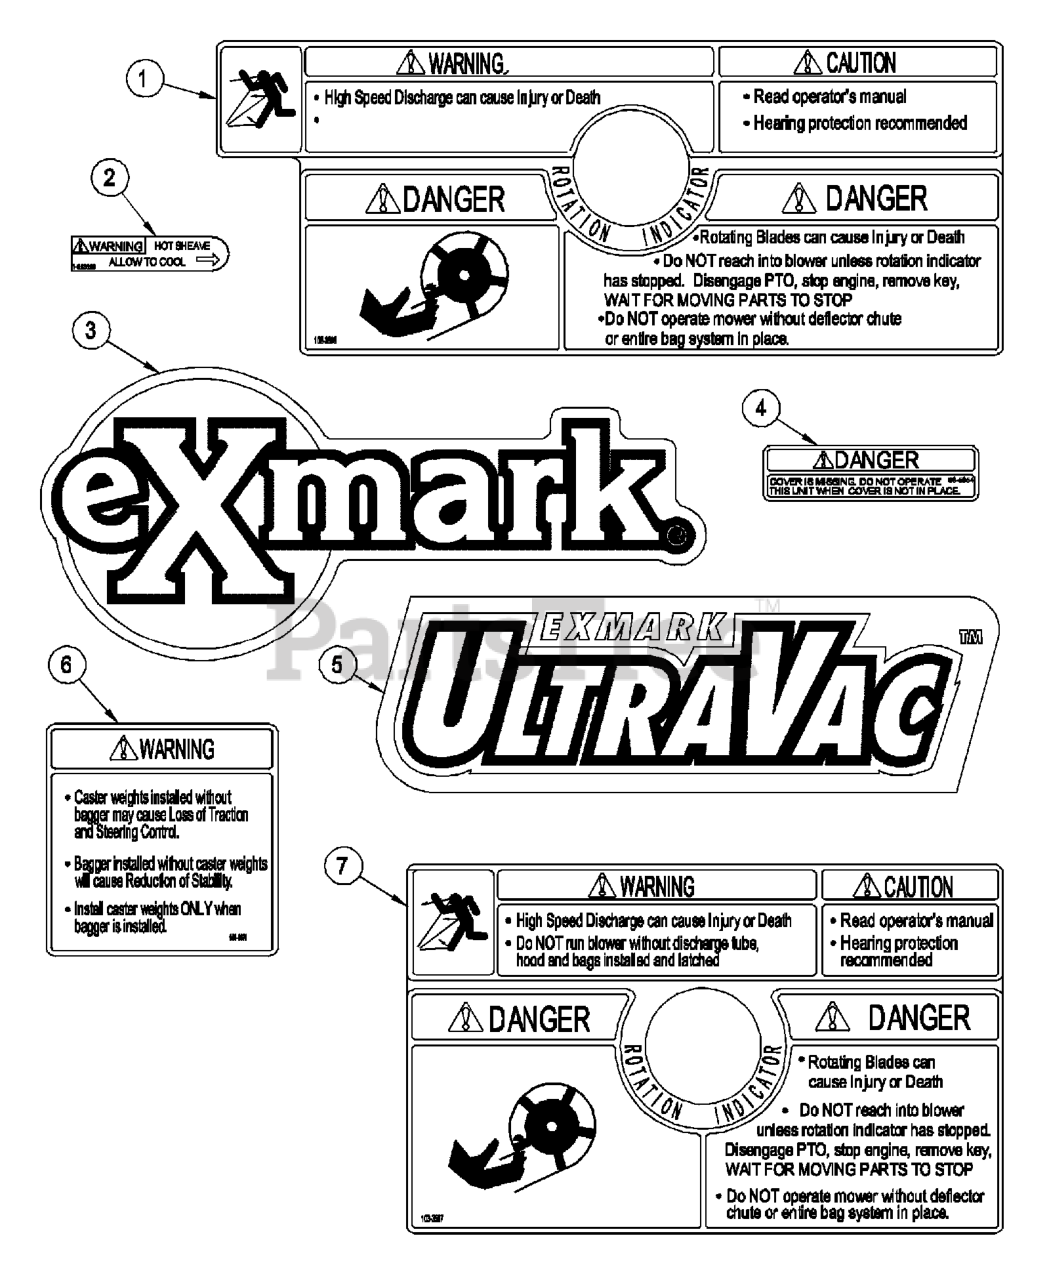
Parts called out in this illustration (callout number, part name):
1	DECAL-WARNING
2	DECAL-WARNING
3	DECAL, EXMARK LOGO
4	DECAL-COVER, MISSING
5	DECAL, ULTRAVAC
